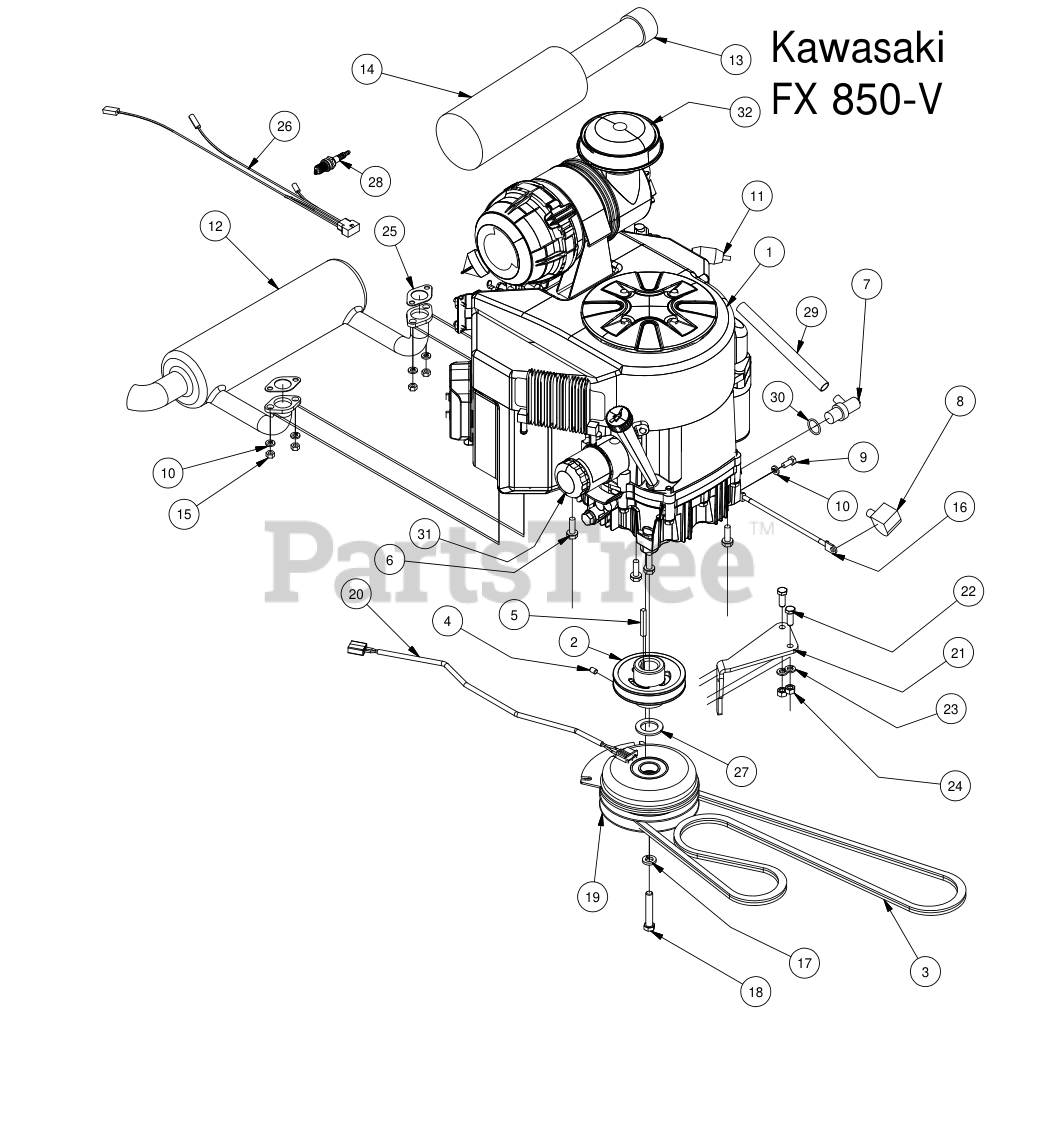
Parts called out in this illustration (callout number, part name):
1	Kawasaki Engine FX-850-V-CS09R
2	4 3/4 Motor Pulley
4	3/8" Set Screw
5	1/4 x 2 Square Stock
6	3/8 x 1 1/8 bolt
8	Black Boot For Ground Cable
9	M8x1.20x20MM Hex head bolt
10	5/16" Lock Washer
11	Universal Inline Fuel Filter
12	Kawasaki Exhaust
13	Canister Air Filter- Inner
14	Canister Air Filter- Outer
15	M8-1.25 Zinc Nut
16	Ground Cable
17	7/16" Lock Washer
18	7/16" x 2 1/2" Hex Bolt
19	Clutch Assembly
20	Clutch Pigtail
21	PTO Engager Holder
22	3/8" x 1" Hex Bolt
23	3/8" Lock Washer
24	3/8" Hex Nut
25	Exhaust Gasket
26	Harness Adaptor
27	1 1/8" Flat Spacer
28	Spark Plug - Kawasaki
29	Oil Drain Hose
31	Kawsaki Oil Filter
32	Kawasaki Rain Cap
